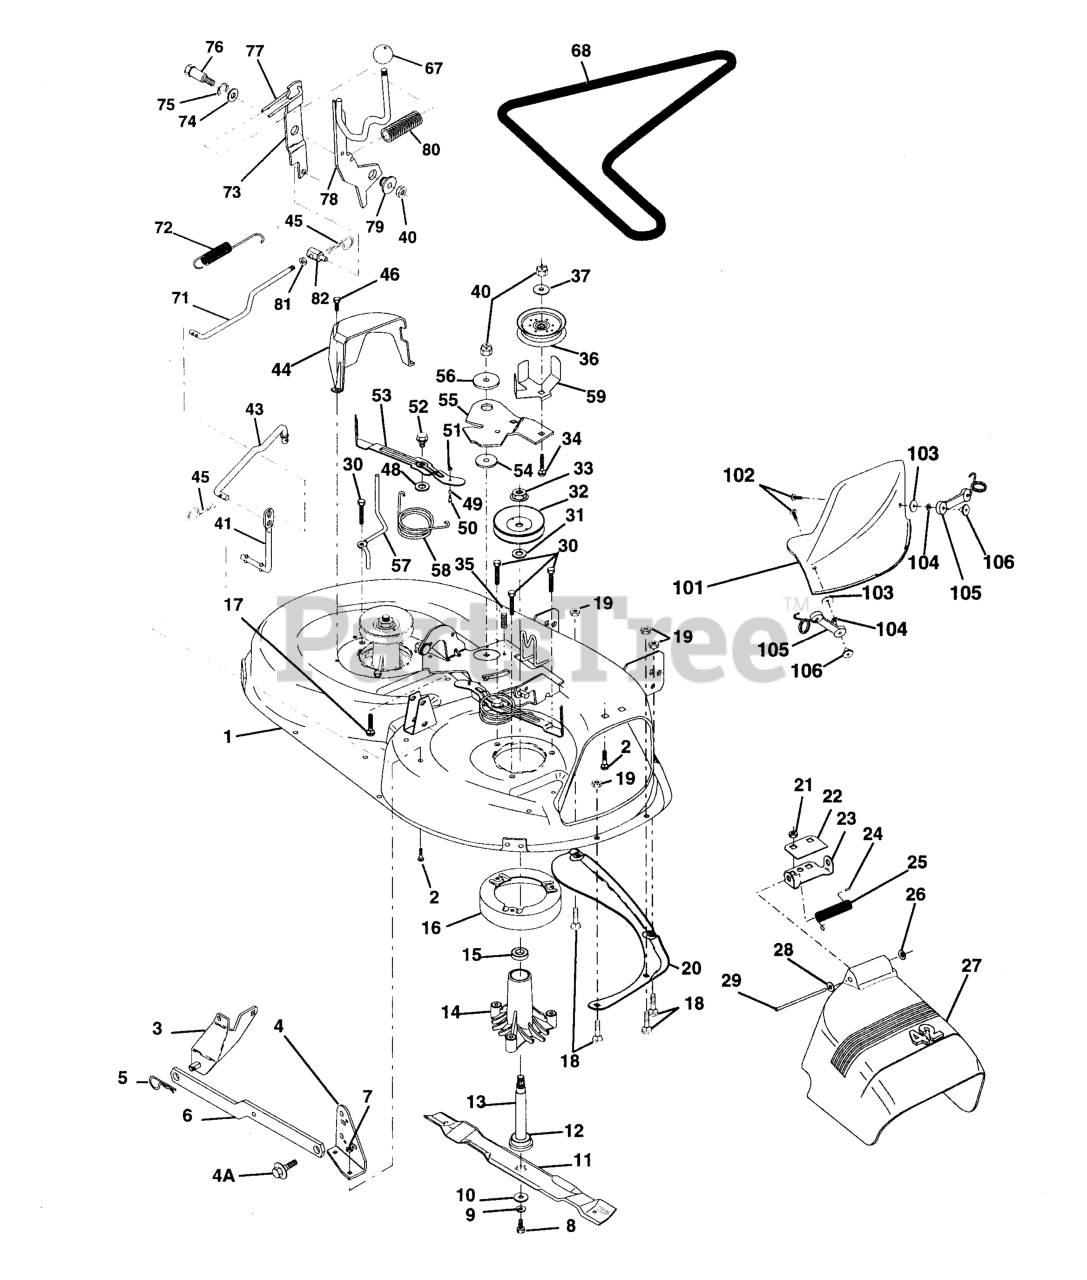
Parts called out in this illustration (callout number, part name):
1	DECK ASM MWR 42"
2	RP BOLT 5/16-18 X3/4 ZN/YEL GR
3	BRKT ASM SWAY BAR
4	BRKT DECK SW BAR
4A	BOLT SHD 5/16-18
5	RETAINER-SPRNG RB
6	REAR SUSP ARM
7	NUT.71038.31-18.HEX.NYLOCK
8	BLADE BOLT
9	LOCKWASHER
10	WASHER.BLADE
11	BLADE.42".MULCH
12	BEARING.BALL.#6204.(MANDREL)
13	SHAFT ASM VENT
14	HOUSING.MANDREL.VENTED (MACHD)
16	STRIPPER
17	BOLT
18	BOLT
19	NUT.71038.31-18.HEX.NYLOCK
20	BAFFLE
21	NUT.71038.31-18.HEX.NYLOCK
22	STIFFENER BRACKET
23	DEFLECTOR BRACKET
24	CAP-SLEEVE LT
25	SPRING TORSION
26	NUT PUSH M
27	SHIELD.DEFLECTOR.MOWER.42".BLK
28	Washer 11/32 X 5/8 X 16 Ga
29	ROD.HINGE
30	SCREW
31	WASHER
32	MANDREL PULLEY
33	NUT
35	FASTENER.XMAS.TREE
36	FLAT IDLER PULLEY
37	WASHER
40	NUT
43	CLUTCH ROD
44	GUARD MANDREL LH BLACK
45	RETAINER M
46	SCREW.1/4-20X5/8
49	CAM FOLLOWER
52	BOLT.SHOULDER.5/16-18
53	ARM
54	HARDENED WASHER
55	IDLER ARM
56	SPACER RETAINER
59	GUARD, BELT
67	KNOB T (1/2-HOLE)
68	RP.V-BELT
71	CLUTCH ROD
72	RETURN SPRING
73	ARM CLUTCH SECONDARY
77	KEEPER SPRING
78	CLUTCH ARM
79	BUSHING.FLANGE.E-RING.GROOVE
80	SPRING
81	NUT
82	TRUNNION.ADJUSTABLE.3/8-16
101	COVER MULCH 42"
102	SCREW
103	LOCKWASHER #10
105	LATCH ASSEMBLY
106	WELDNUT
